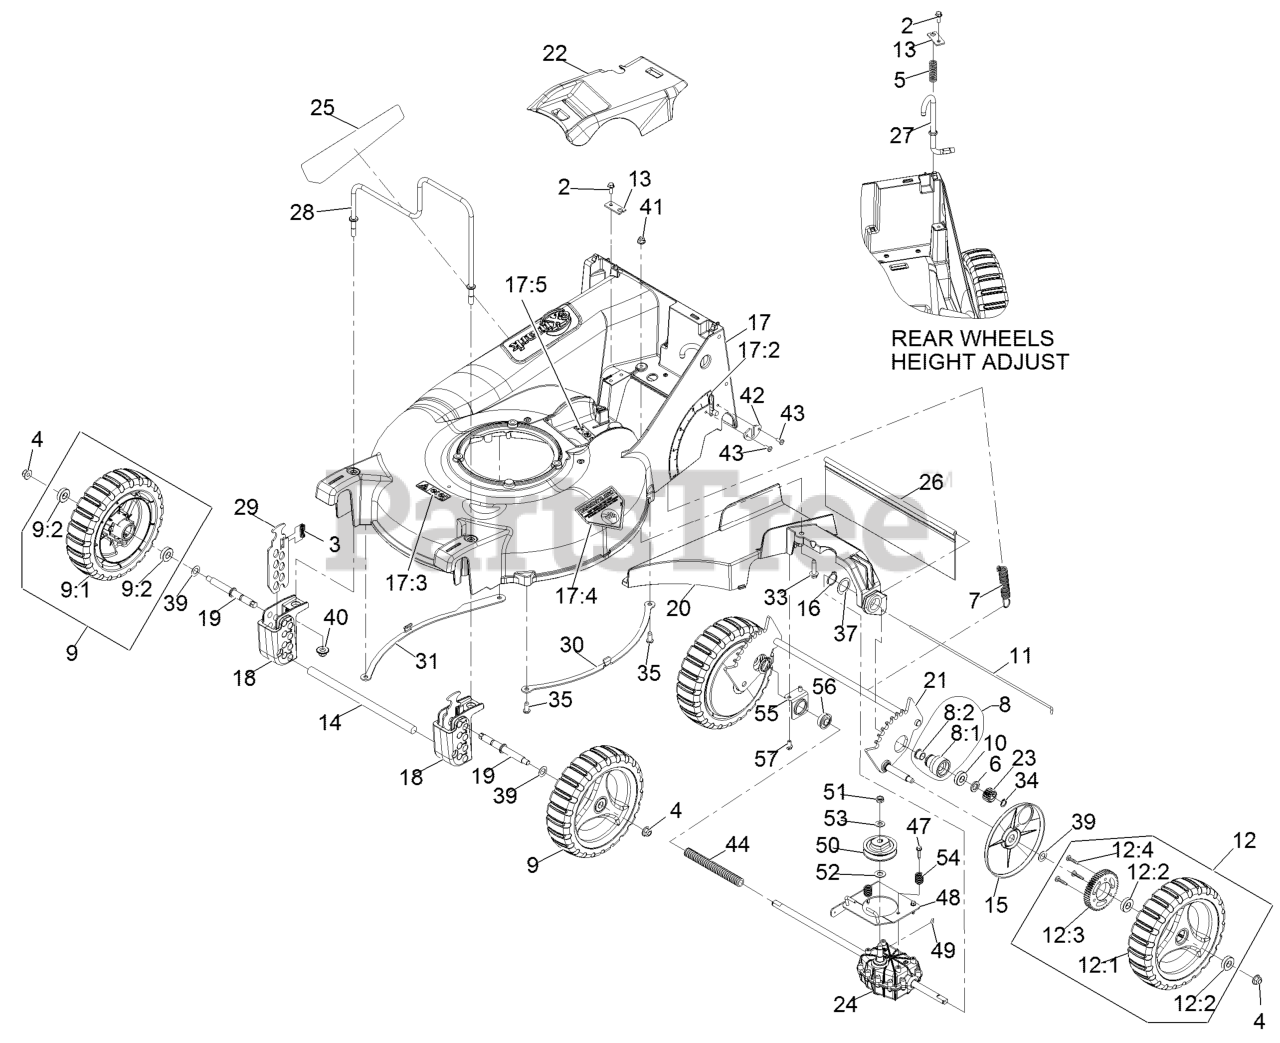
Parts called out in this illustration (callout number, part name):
2	SCREW-HWH
3	SPRING-COMPRESSION
4	NUT-HF, NI
5	SPRING-COMPRESSION
6	SPACER-BUSHING
7	SPRING-EXTENSION
8	HOUSING ASM
8:1	HOUSING-BEARING
8:2	BEARING-FLANGE
9:2	BEARING-BALL
10	BEARING-BALL
11	ROD,SHIELD
12:2	BEARING-BALL
12:4	SCREW-DRIVE
13	BRACKET,MOUNT
14	ROD,BUMPER
15	COVER,GEAR
16	RING-RETAINING
17	DECK W/DECALS
17:2	DECAL-HEIGHT OF CUT
17:3	DECAL-WARNING, BLADE
17:4	DECAL-DANGER
17:5	DECAL-DANGER
18	BLOCK,FRONT QUADRANT
19	AXLE-WHEEL
20	BRACKET-TRANSMISSION AND
21	WLD,REAR AXLE P21
22	COVER,BELT
24	TRANSMISSION-HD, 4.5/1
25	DECAL-COMM 21 X-SERIES
26	SHIELD-TRAILING P21
27	ROD-HEIGHT ADJ P21
28	GUARD,ENGINE
29	PLATE, FRONT HEIGHT
33	SCREW-HWHTF
34	RING-RETAINING
35	SCREW-BHTF
39	WASHER-PLAIN
40	Nut-Nyloc 3/8-16 Flg
41	NUT-HF, NI
42	PLATE,WEAR
43	RIVET-BLIND
44	COVER-SHAFT-DRIVE
47	SCREW-SPECIAL
48	TRANSMISSION PLATE ASM
49	KEY-WOODRUFF
51	NUT-HEX
52	WASHER-THRUST
53	WASHER-FLAT
54	SPRING,COMPRESSION
56	BEARING-BALL
57	SCREW-HWH
